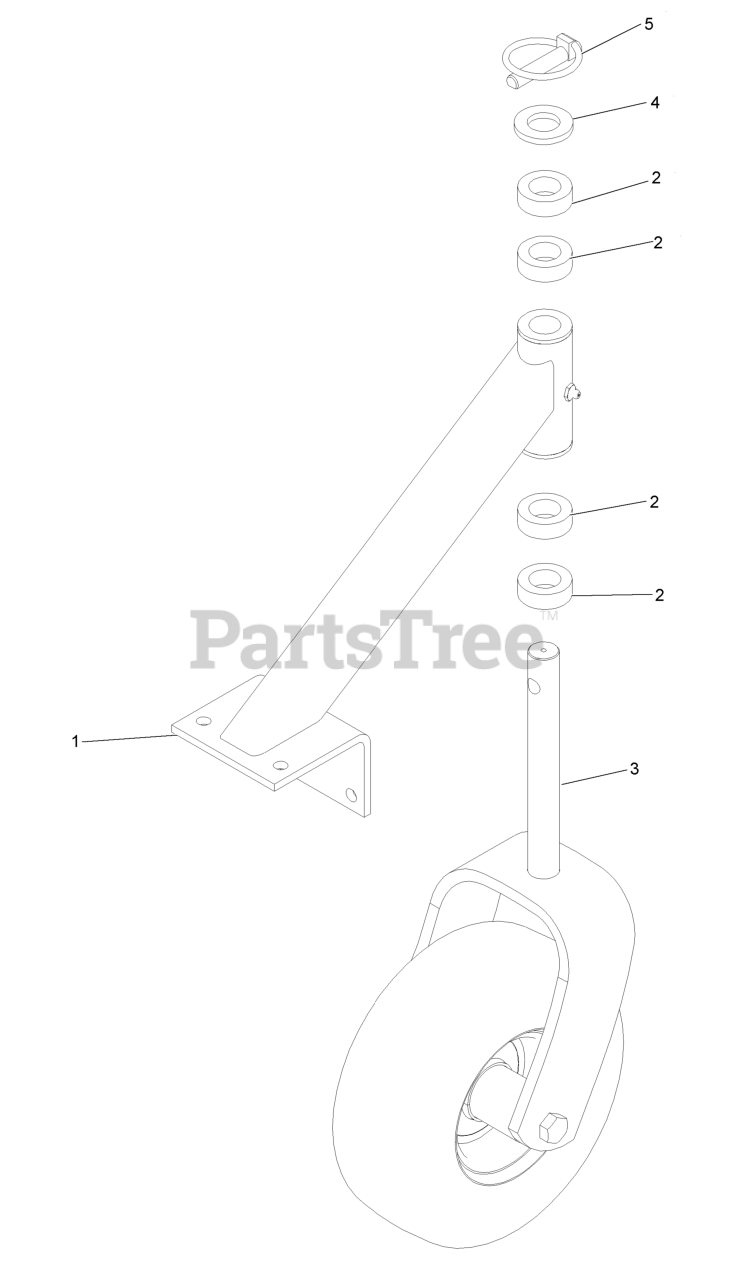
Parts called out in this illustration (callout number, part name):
1	Caster Whl Support W/Bearings, Weighted
2	Spacer-Caster
3	Caster Wheel Assembly
